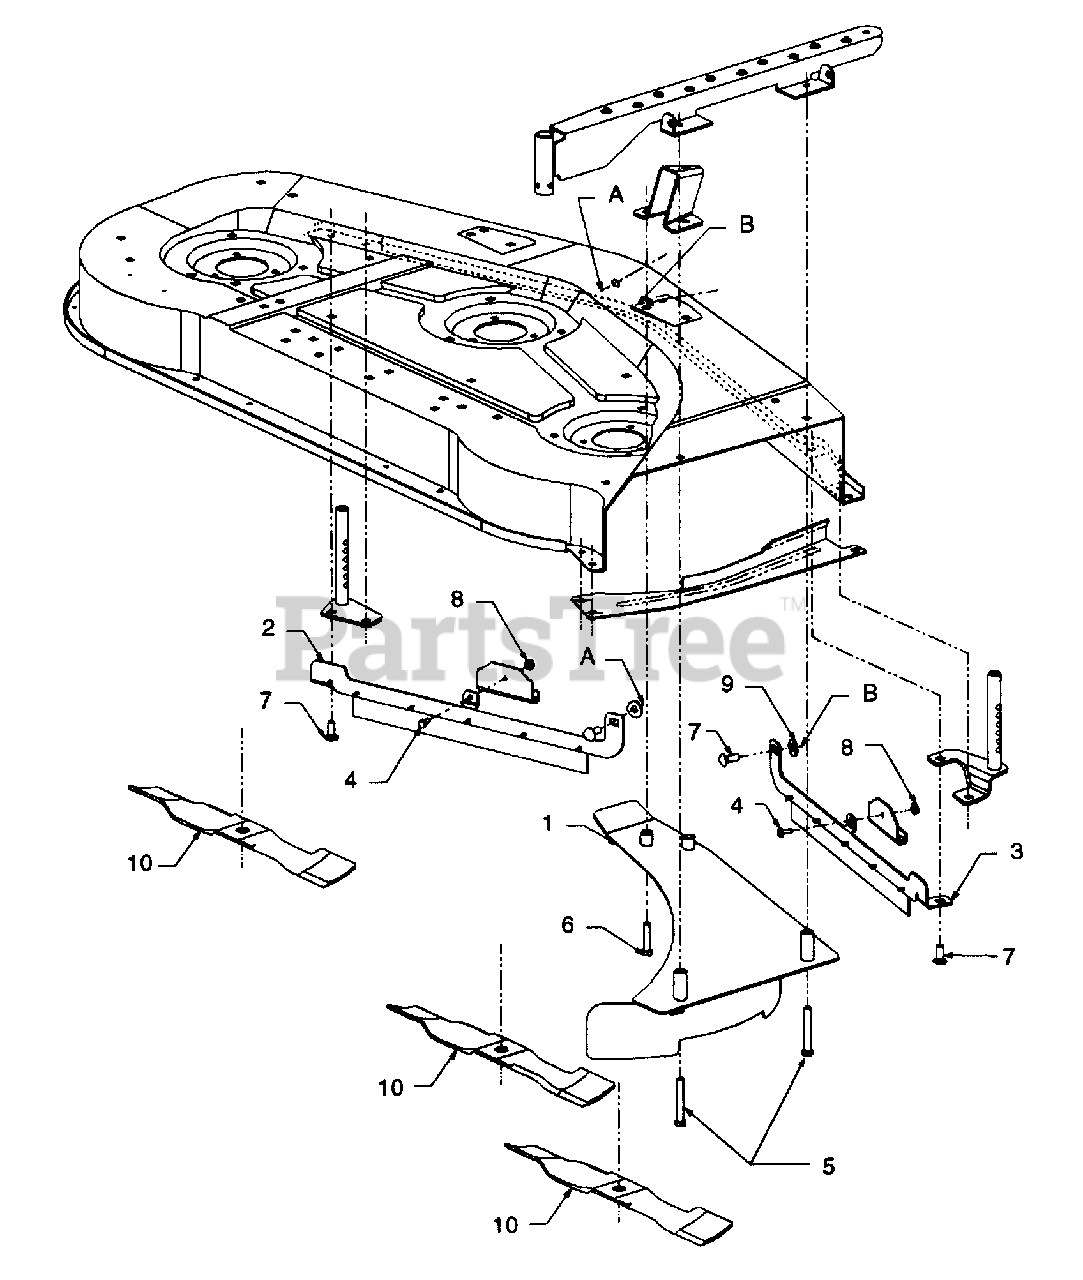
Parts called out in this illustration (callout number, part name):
1	Baffle Ass'y, 54" Mulching
5	Screw, Hex Cap, 3/8-16 X 2-3/4 GR5
6	Screw, Hex Cap, 3/8-16 X 1-3/4 GR5
7	Bolt, Carriage, 3/8-16 X 1.0 GR5
8	Nut, Hex Flange Lock, 1/4-20
9	Washer, Flat, .406 X 1.0 X .105
10	Blade, Mulching, 18.5 Lg
